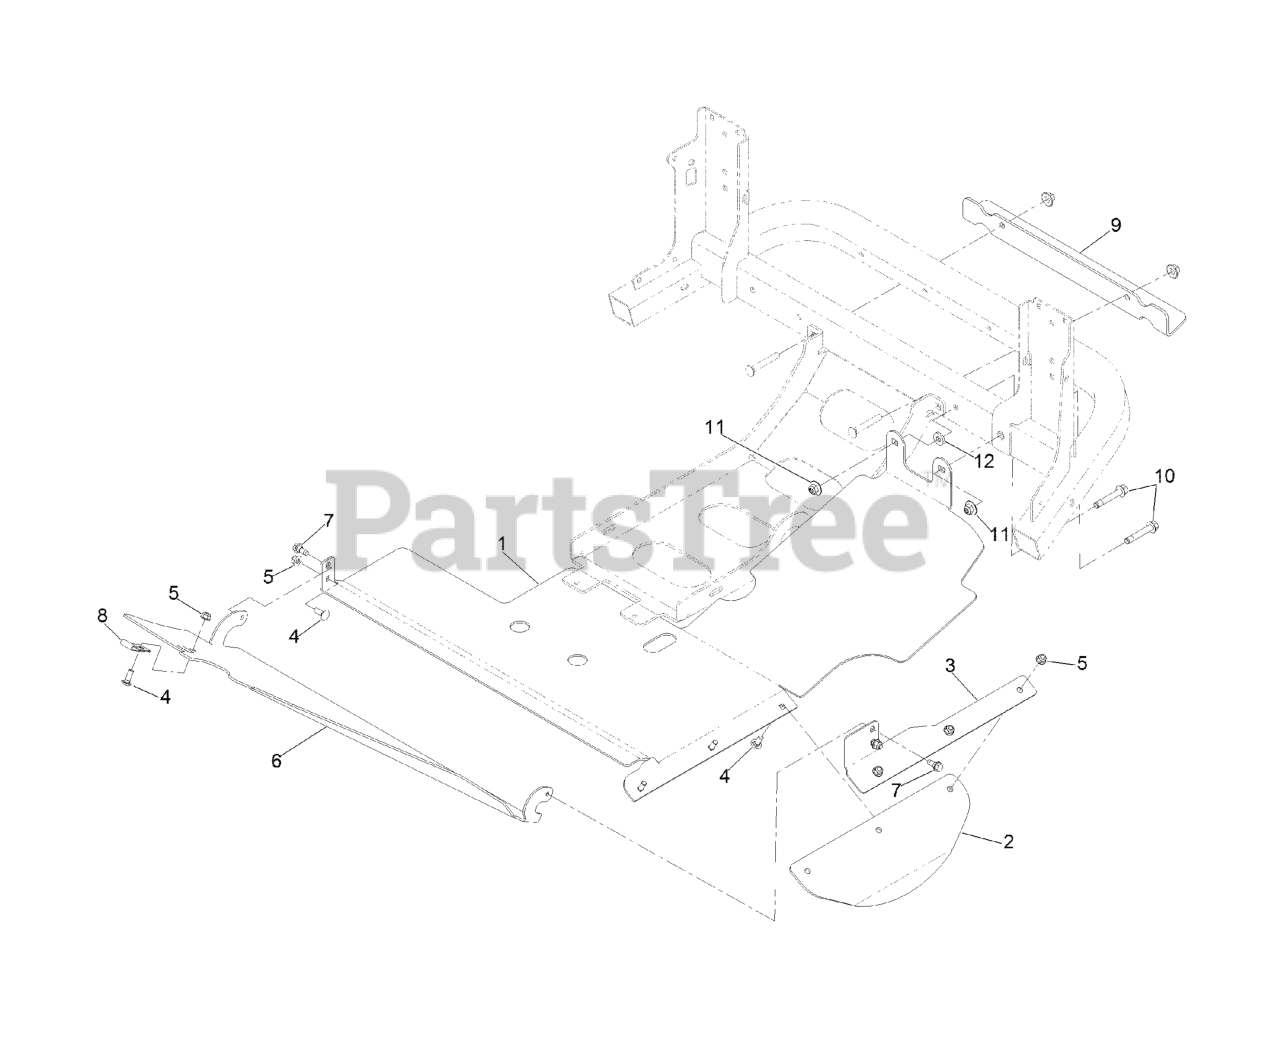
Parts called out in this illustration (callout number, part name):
1	PLATE-DISCHARGE
2	FLAP-RUBBER
3	BRACKET-FLAP, LH
4	SCREW-CARR
5	NUT-HF, NI
6	PANEL-DISCHARGE
7	SCREW-SHOULDER
8	BEARING-STRAP, NYLON
9	BRACKET-TIE DOWN
10	SCREW-HHF
11	Nut-Nyloc 3/8-16 Flg
